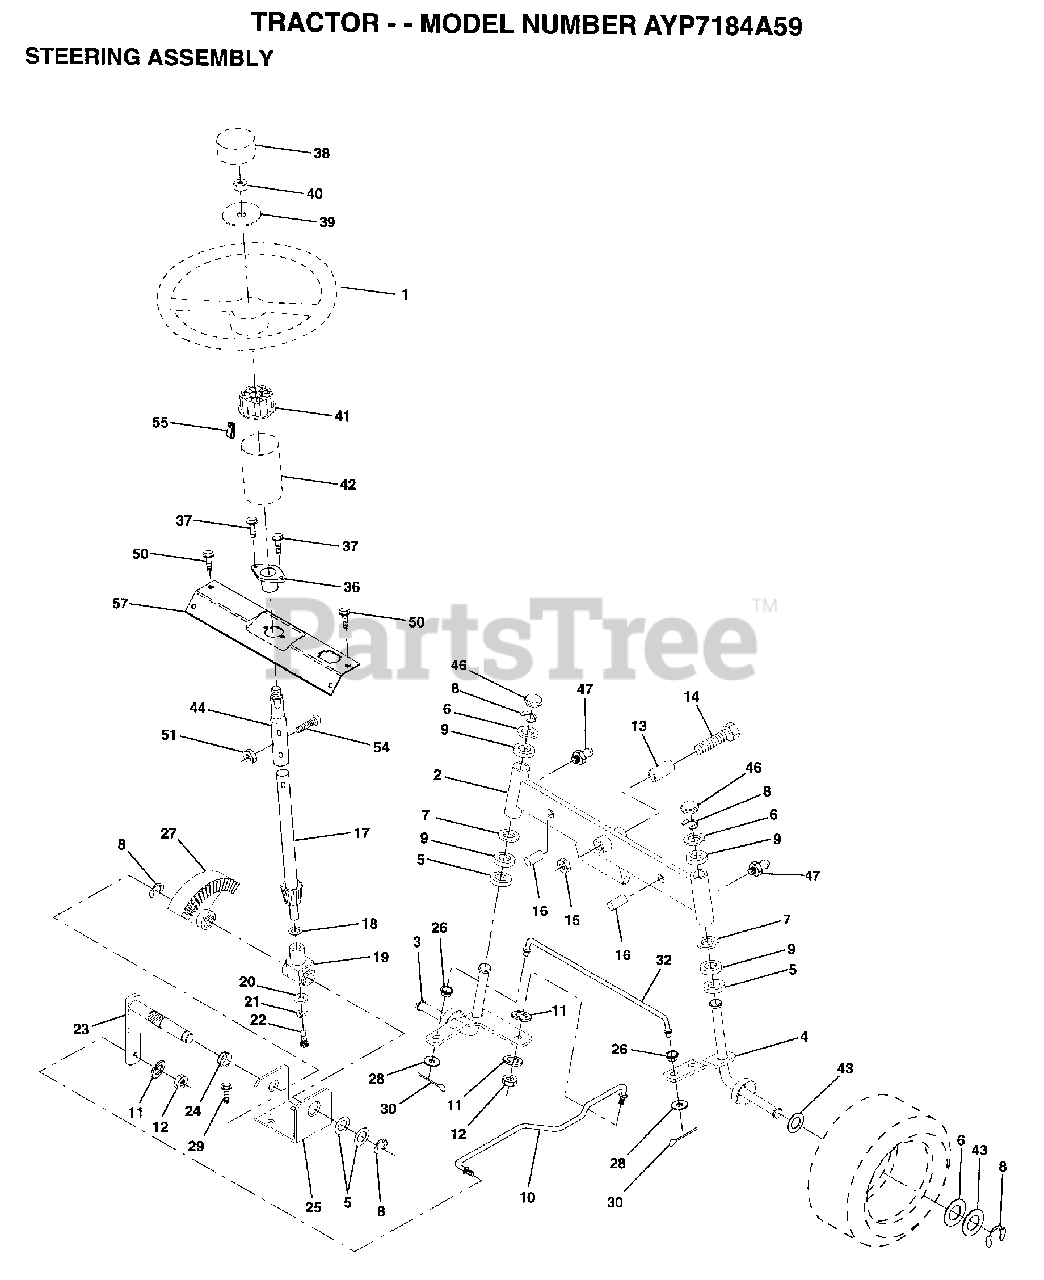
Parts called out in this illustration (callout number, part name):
1	WHEEL STR AYP BLK
2	AXLE ASM FRONT
3	SPINDLE LH
4	SPINDLE RH
5	WASHER .T
6	WASHER
7	WASHER
8	RING
9	COL. SRTG. BEAR.
11	LOCKWASHER
13	BEARING
14	BOLT HEX 5/8-11
15	"NUT-LOC,FLANGE LT"
16	AXLE PIN
17	SHAFT ASM STEERIN
18	THRUST WASHER
19	SUPPORT.SHAFT
21	LOCKWASHER
22	"SCREW,SPECIAL"
24	NYLINER T
25	"BRKT,STEERING"
26	BUSHING.DRAGLINK
27	GEAR SECTOR
28	WASHER
29	SCREW
30	COTTER PIN
32	TIE ROD
38	CAP STEER AYP
39	WASHER T
40	GRIPCO NUT
41	ADAPTER-WHEEL LT
42	BOOT SHAFT STEER
43	WASHER
44	SHAFT EXT STEER
46	CAP
47	ZERK M
50	SCREW HEX CRT
51	NUT
54	BOLT
55	CLIP TINNERMAN
57	SUPPORT SHAFT STR
